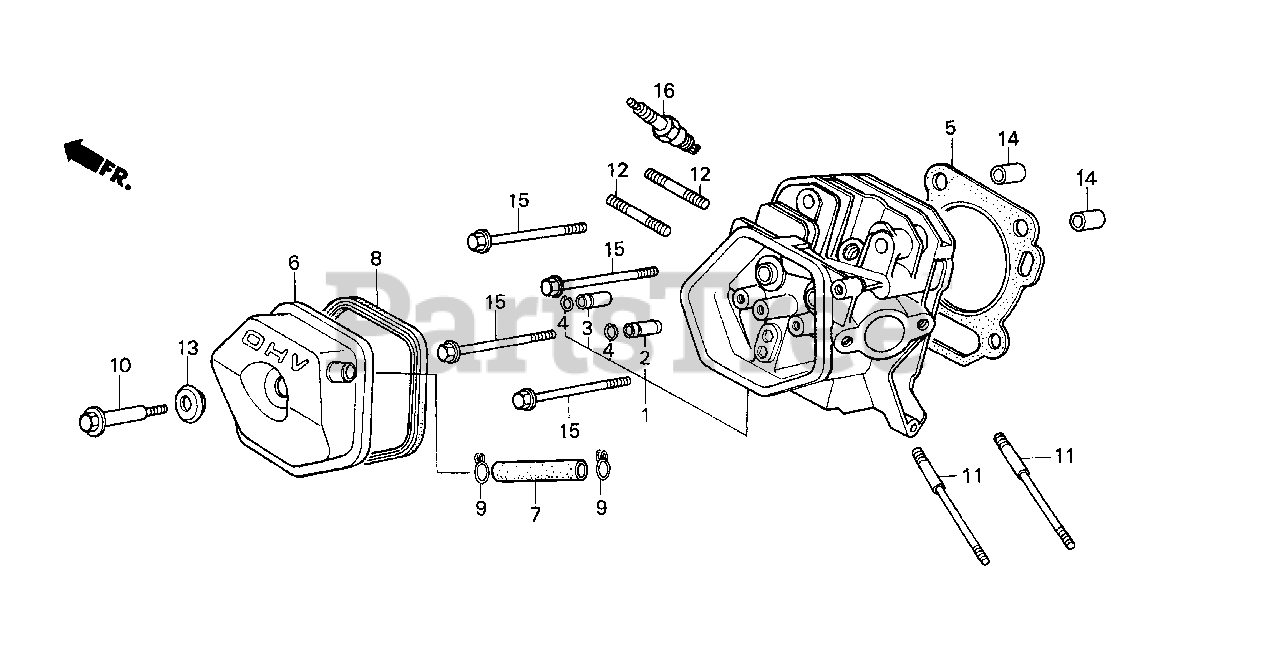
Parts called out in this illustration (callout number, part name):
1	CYLINDER HEAD
2	GUIDE, VALVE (OS)
3	GUIDE, EX. VALVE (OS)
4	CLIP, VALVE GUIDE
5	GASKET, CYLINDER HEAD
6	COVER KIT, HEAD
7	TUBE, BREATHER
8	GASKET, CYLINDER HEAD COVER
8	GASKET, HEAD COVER
9	CLIP, BREATHER TUBE
10	BOLT, HEAD COVER
11	BOLT, STUD (8X131.5)
12	BOLT, STUD (8X40)
13	WASHER, HEAD COVER
14	PIN, DOWEL (12X20)
15	BOLT, FLANGE (10X80)
16	SPARK PLUG (BPR5ES-11) (NGK)
16	SPARK PLUG (W16EPR-U11)
16	SPARK PLUG (BPR6ES-11) (NGK)
16	SPARK PLUG (W20EPR-U11) (DENSO)
